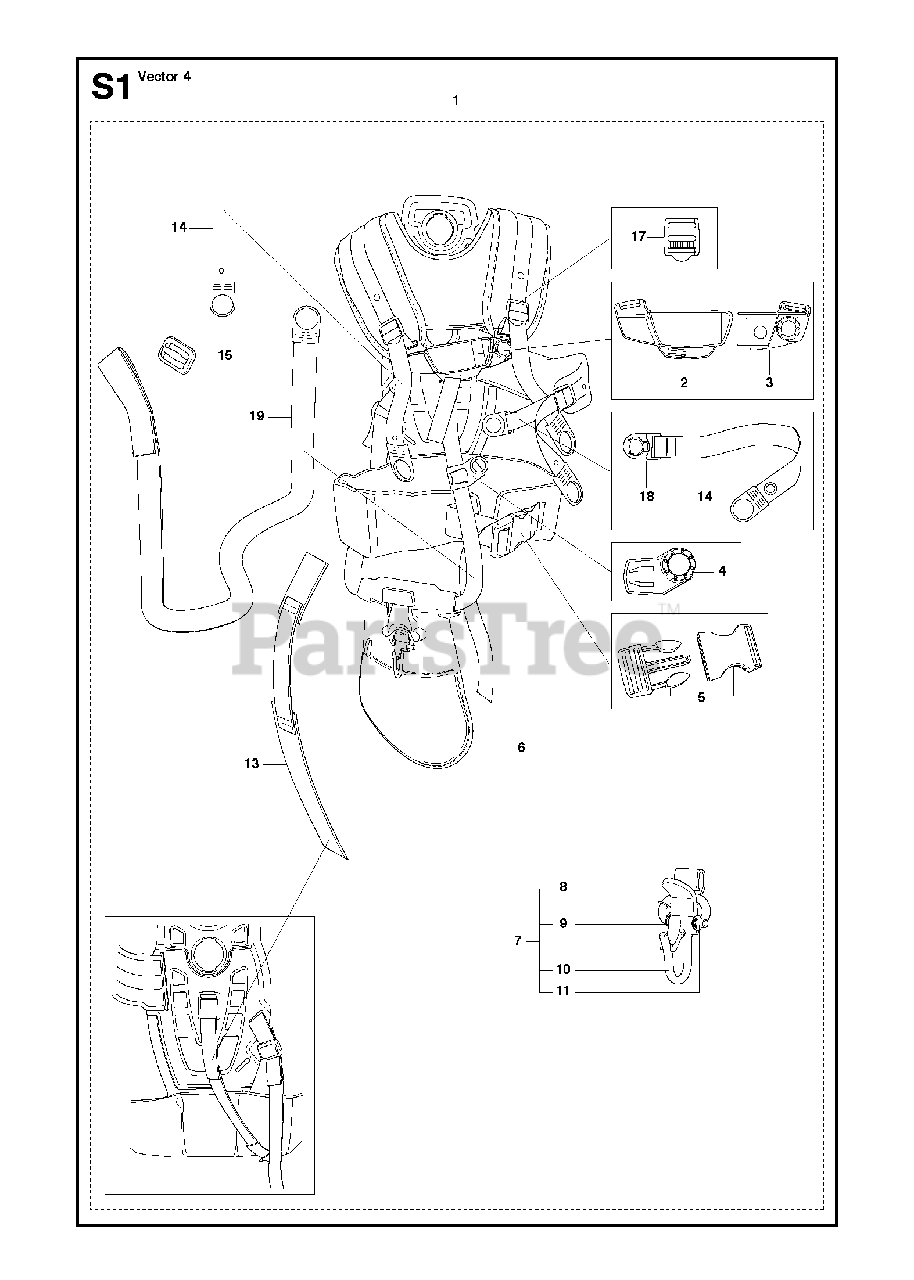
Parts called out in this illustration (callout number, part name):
5	BUCKLE
7	WELT HOOK
8	CATCH *
9	SPRING
10	HOOK
11	E-RING 5
15	CLIP
17	BUCKLE
18	SNAP LOCKING
